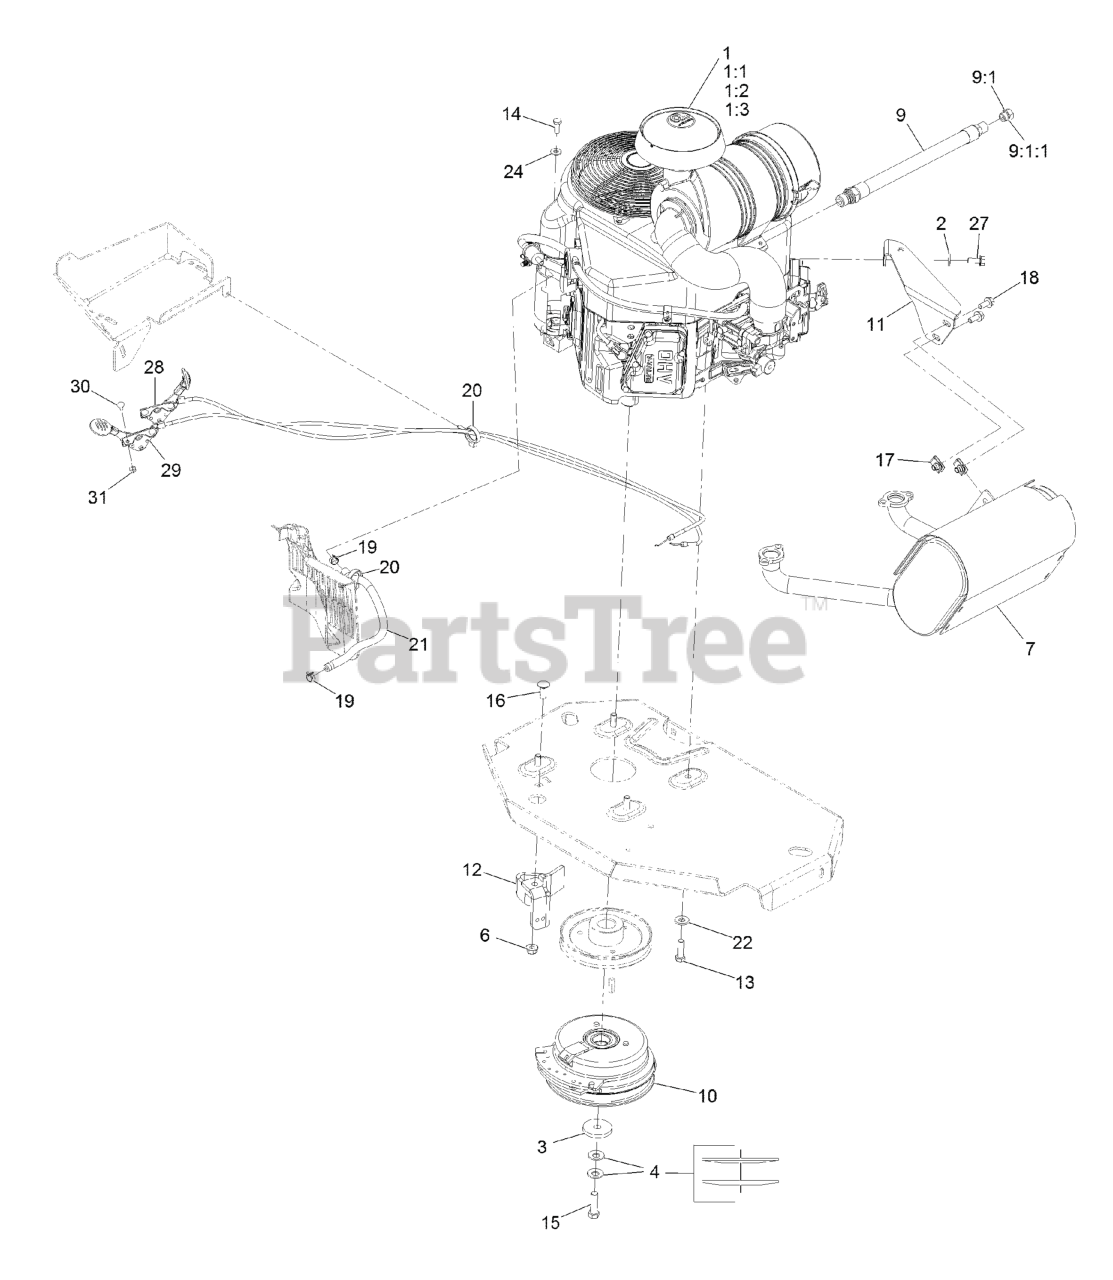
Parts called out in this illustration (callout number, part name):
1:1	Kohler 52 050 02-S Engine Oil Filter
1:2	Kohler 25 083 01-S Engine Air Filter
1:3	Kohler 25 083 04-S Safety Filter
3	CLUTCH KIT
4	WASHER-CLUTCH
5	WASHER-SPRING
6	SCREW-HH 7/16-20 X 1 1/2 W/LOCTITE
7	SCREW-CARR
8	MUFFLER BRACKET KIT
9	MUFFLER KIT
10	SCREW-HWH
11	WASHER-BELLEVILLE
12	OIL DRAIN HOSE ASM
12:2	PLUG-HH
12:2:1	O-RING
13	SCREW-HHF
15	NUT-HF, NI
16	CLUTCH-ANCHOR
18	FUEL LINE ASM
18:1	HOSE-FUEL
18:2	SLEEVE-THERMAL
18:3	CLAMP-HOSE
19	SCREW-HH M6-1 X 20Mm W/Patch
20	WASHER-SPRING
21	ASM,THROTTLE CABLE
22	BOLT-CARR
23	NUT-LOCK, NI
24	CLAMP-HOSE
